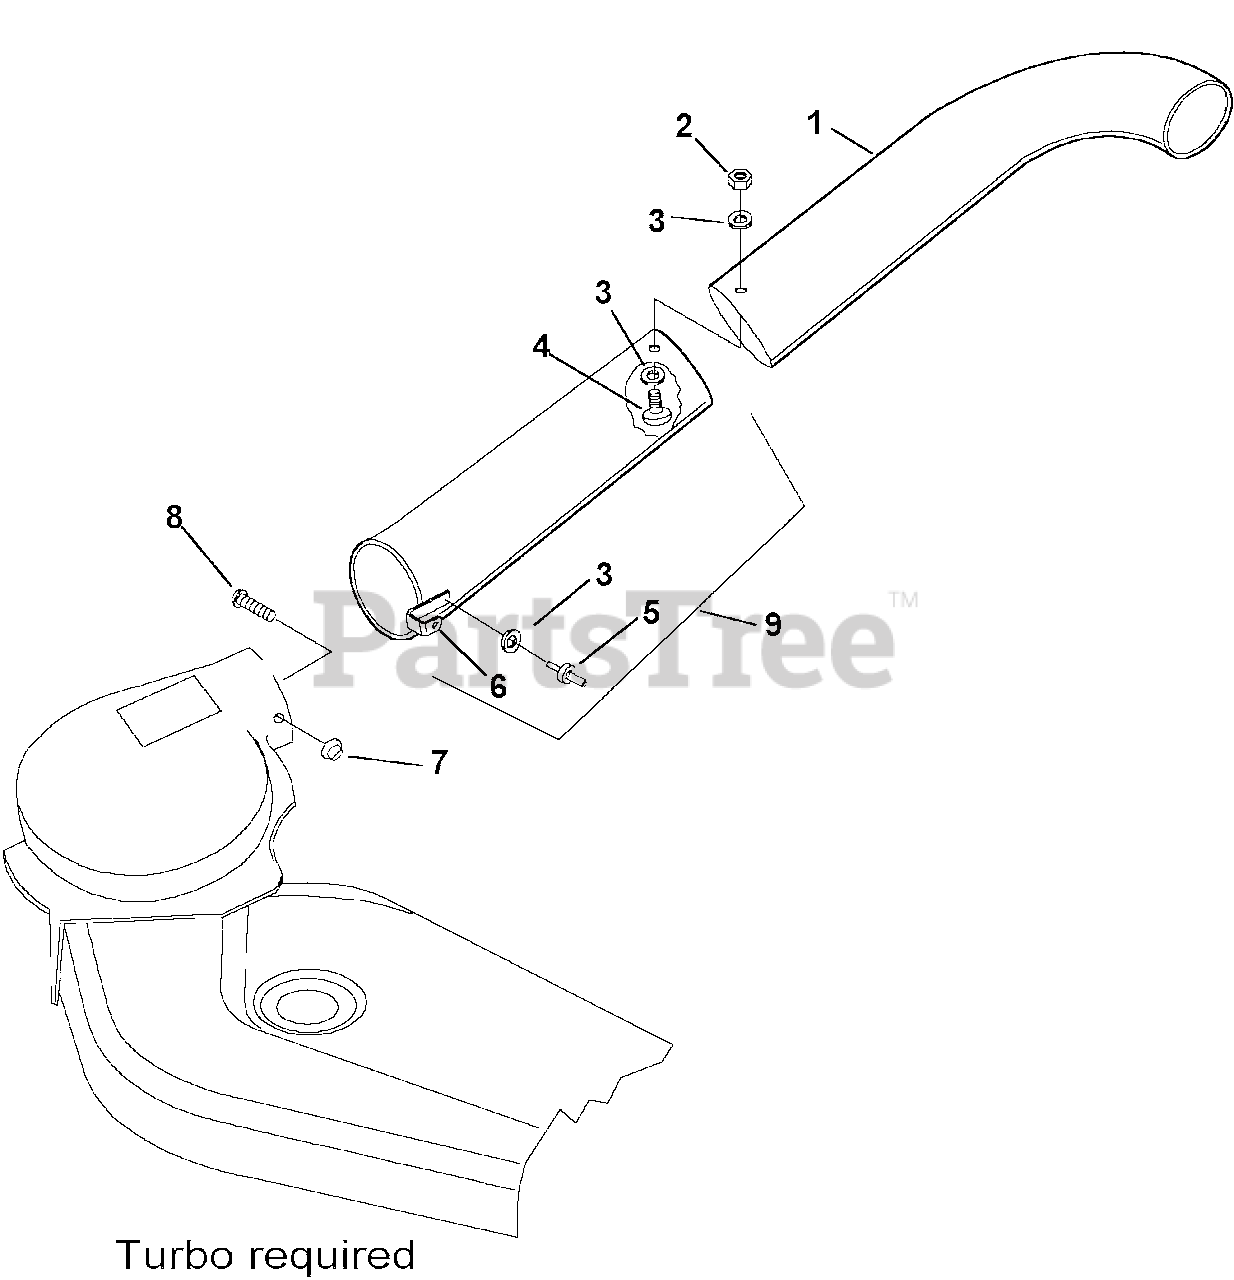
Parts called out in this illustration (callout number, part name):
1	ELBOW, Upper
2	NUT-HEX & WASHER ASMY
4	SCREW, Truss Head, #10-32 x 1/2
6	CLIP, Spring
7	LOCKNUT, Hex, Flange, 1/4-20
8	BOLT-RD HD SH SQ NK 1
9	TUBE & SPRING ASSEMBLY (Incl. Ref. Nos. 3, 5, & 6)
